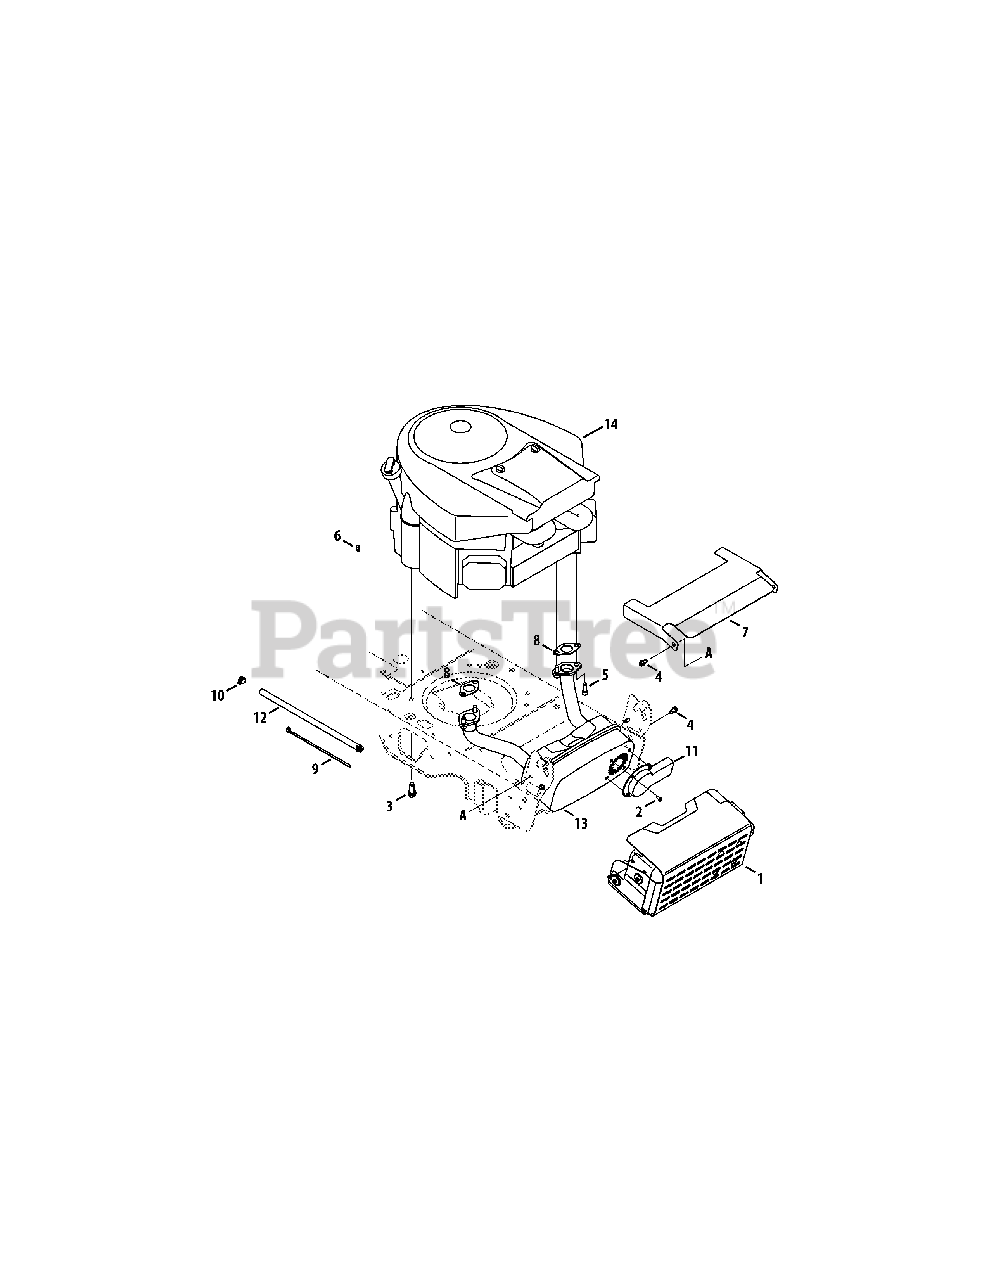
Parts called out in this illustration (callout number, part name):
1	Mulffler Shield Assembly
2	Screw, Indented Washer, #8-18:0.500
3	Taptite Screw, Indented Washer, 3/8-16:1.000
4	Taptite Screw, Indented Washer, 1/4-20:0.500
5	Socket Head Screw, 5/16-18:.750
6	Sems Nut, 1/4-20
7	Heat Shield
8	Exhaust Gasket
9	Cable Tie, 3/16 X .05 X 7.4
10	Hose Clamp, .490 DIA.
11	Long Muffler Deflector
12	Fuel Hose
13	Muffler
14	Replacement Engine - 44P777-2799-G1
